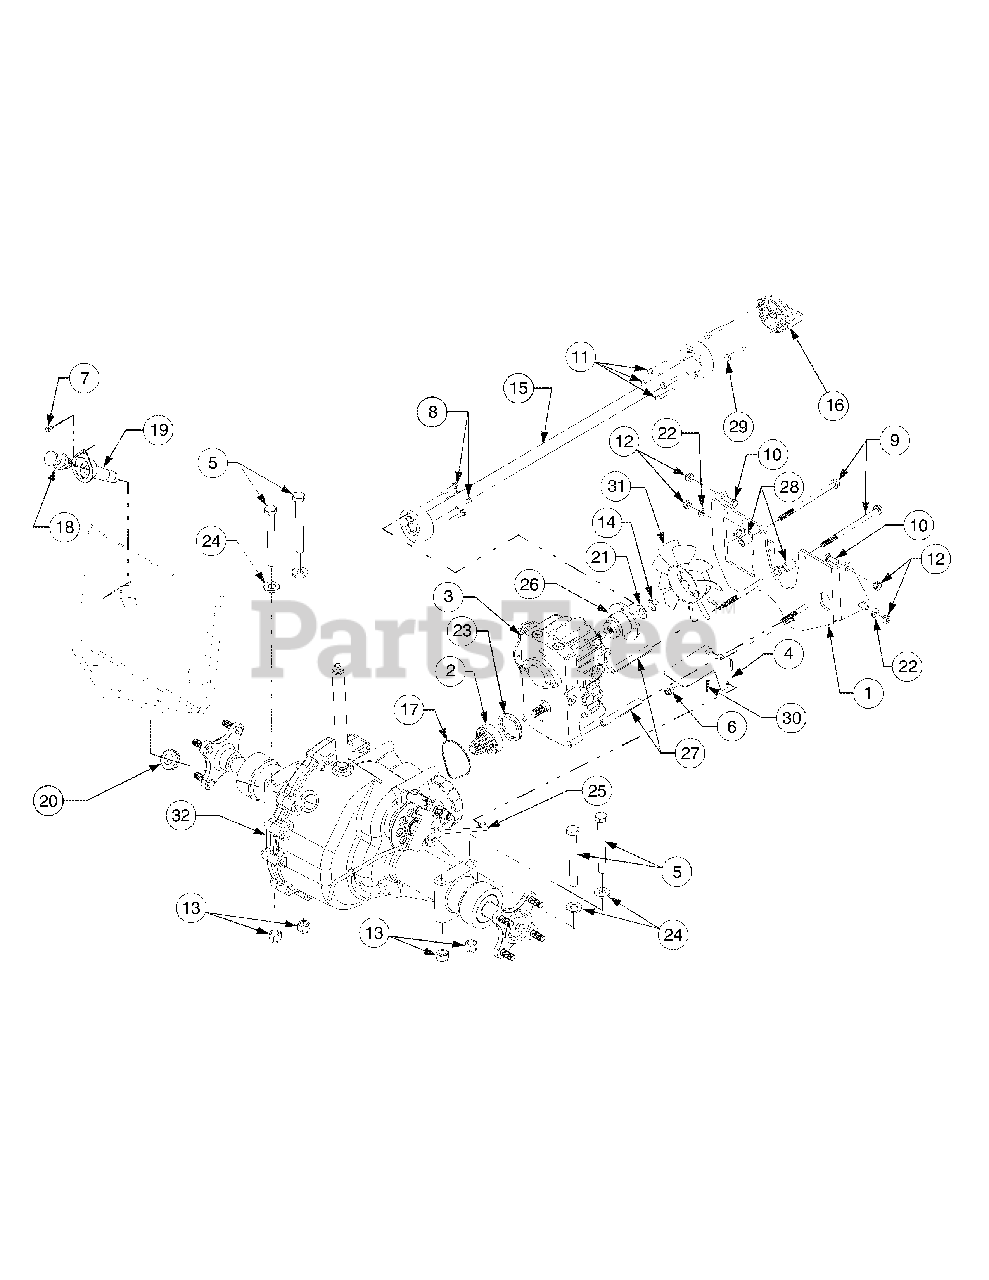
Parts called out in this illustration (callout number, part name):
1	Bracket, Torque
2	Gear Assembly, Pinion
3	Transmission, Hydrostatic
5	Screw, Hex Cap, 1/2-20 x 4.5 GR5
6	Scrw, Hx Wsh Hd Tapp, 1/4-20 x 5
7	Scrw, Hx Wsh Hd Tapp, 10-16 x .44
8	Screw, Hex Patch, 1/4-20 x 1.25 GR5
9	Scrw, Hx Hd Tapp, 5/16-18 x 5.25
10	Screw, Hex Cap, 5/16-18 x .75 GR5
11	Screw, Hex Patch, 1/4-20 x 1.62 GR5
12	Nut, Hex Cntr Lock, 3/8-16
13	Nut, Hex Nylon Lock, 1/2-20 GR2
14	Nut, Hex Top Lock Jam, 1/2-20
15	Shaft, Drive, 30.875 Lg
16	Adapter, Engine
17	Seal, Gland
18	Dipstick, Transmission
19	Holder, Dipstick
20	Grommet, Rubber, .75 x 1.063
21	Washer, Belleville
22	Washer, Flat, .344 x .688 x .065
23	Washer, Spring
24	Washer, Flat, .531 x 1.062 x .134
25	Rod, Hydro Dump Valve
26	Adapter, Hydro Pump
27	Spacer, Hydro, .323 x .443 3.51
28	Spacer, Hydro, .323 x .600 x .74
29	Screw, Hex Patch, M10-1.50 x 90mm
30	Internal Cotter Pin
31	Fan, Pump
32	See "Hydro Transmission" for Parts Info.
